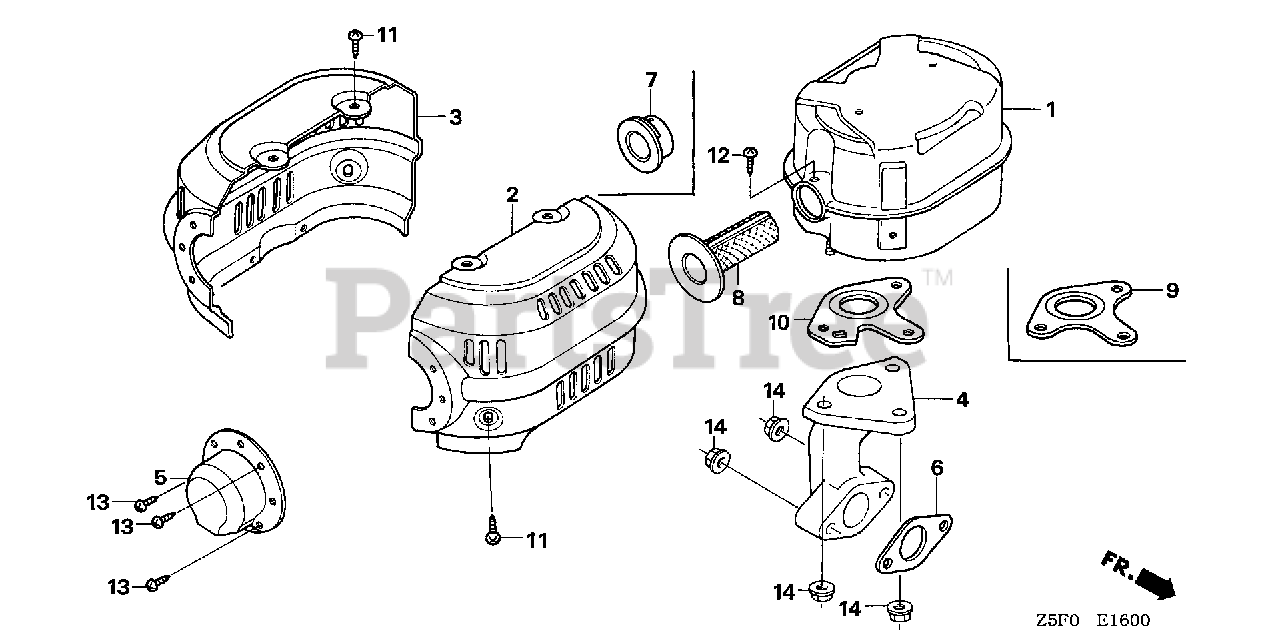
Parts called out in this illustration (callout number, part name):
2	PROTECTOR, R. MUFFLER (STD)
3	PROTECTOR, L. MUFFLER (STD)
6	GASKET, EX. PIPE
8	ARRESTER, SPARK
10	GASKET, MUFFLER (ARRESTER) (NIPPON LEAKLESS)
11	SCREW, TAPPING (5X8)
12	SCREW, TAPPING (5X8)
12	SCREW, TAPPING (4X6)
14	NUT, FLANGE (8MM)
